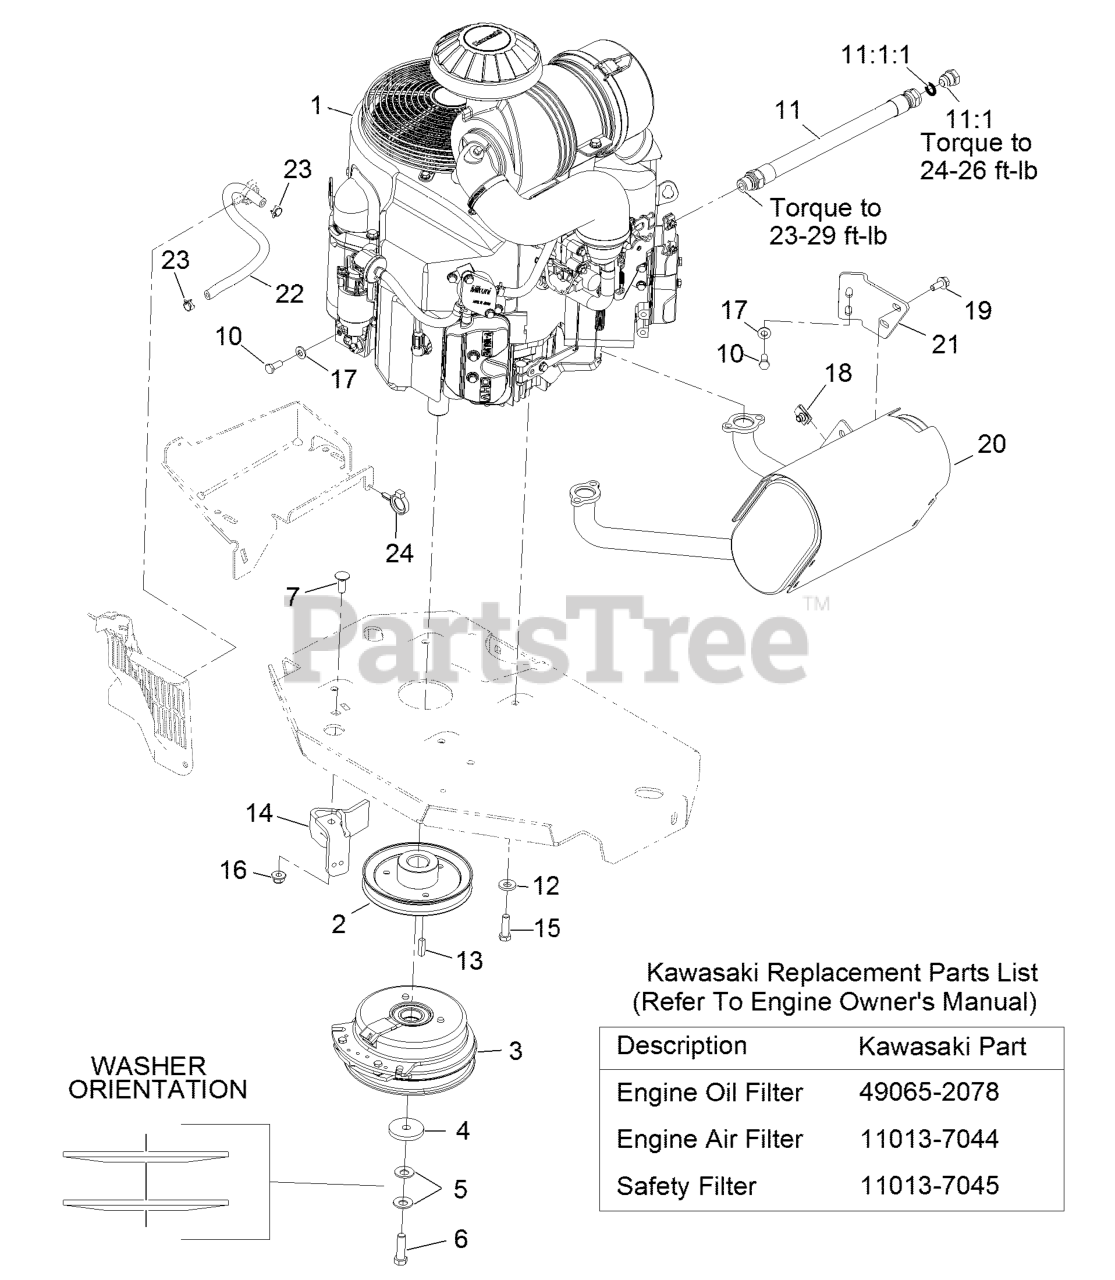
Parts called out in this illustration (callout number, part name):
2	SHEAVE
3	CLUTCH KIT
4	WASHER-CLUTCH
5	WASHER-SPRING
6	SCREW-HH 7/16-20 X 1 1/2 W/LOCTITE
7	SCREW-CARR
10	SCREW-HH
11	ENGINE OIL DRAIN HOSE ASM
11:1	PLUG-HH
11:1:1	O-RING
12	WASHER-BELLEVILLE
14	CLUTCH-ANCHOR
15	SCREW-HH
16	NUT-HF, NI
17	WASHER-SPRING
19	SCREW-HHF
20	MUFFLER
21	BRACKET-MUFFLER
22	HOSE-FUEL
23	CLAMP-HOSE
24	CLAMP-HOSE
